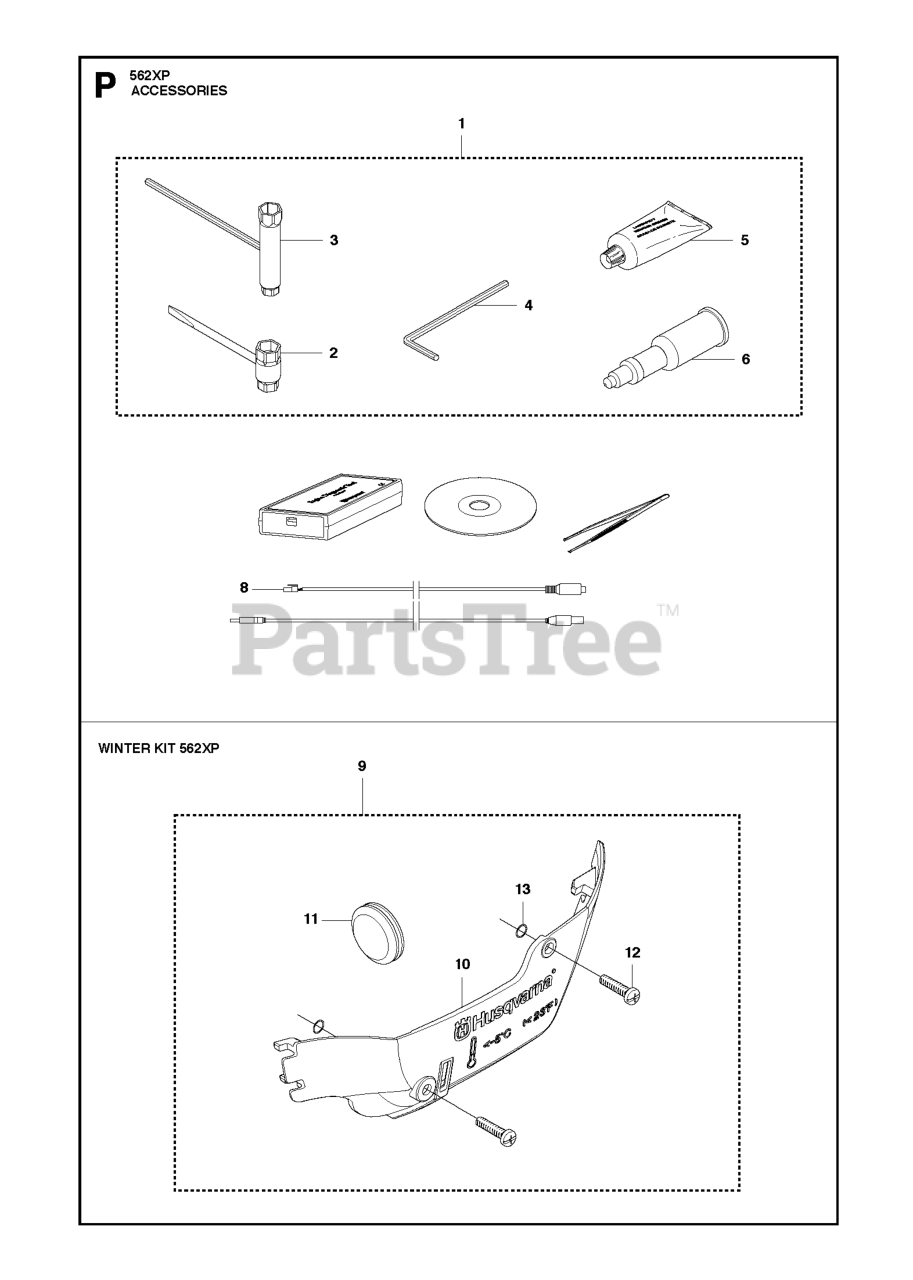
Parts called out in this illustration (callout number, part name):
2	COMBINATION WRENCH
3	L-SPANNER
4	L-SPANNER
5	GREASE
6	Grease Gun
7	SERVICE TOOLS
8	CABLE ASSY
9	WINTER KIT
10	WINTER COVER
11	PLUG
12	SCREW
13	O-RING
14	SPIKE OUTER
15	SCREW
16	SPIKE OUTER
17	SPIKE OUTER
